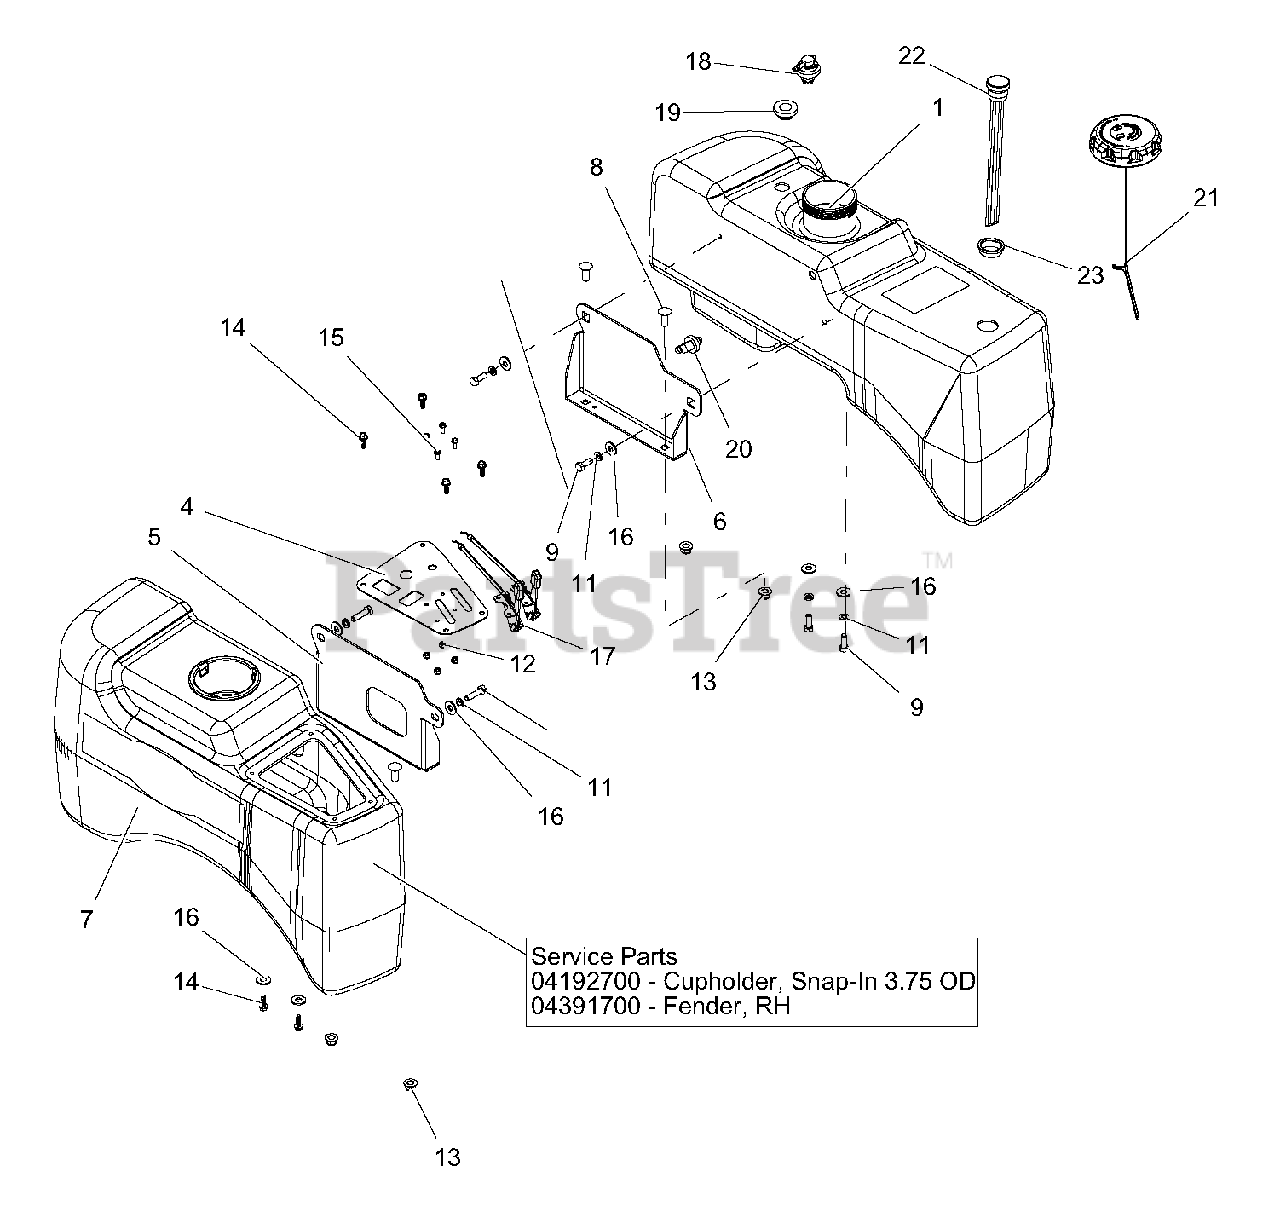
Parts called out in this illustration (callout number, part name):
1	HD, FUEL TANK ASSEMBLY
4	PANEL, INSTRUMENT-BLACK
5	BRKT, RH HD FUEL TANK MTG-RED
6	BRKT, LH HD FUEL TANK MTG-RED
7	ASM, FENDER W/CUPHOLDER
8	BLT-RDHDSQNK .38-16X1.00 G5 YWZC
9	BLT-HEX .31-18X.875 GR5 YWZC
10	BLT-HEX .31-18X1.25 GR5 YWZC
11	WSHR-LK .31X.078 REG YWZC
12	NUT-LK-NYL #10-24 YWZC
13	NUT-LK-NYL-FLG .38-16 YWZC
14	SCR-PLASTITE .25-10X.75 YWZC
15	SCR-MCH 10-24X.50 HWH YWZC
16	WSHR-FL-STL.38X.875X.083 YWZC
17	CABLE, CONTROL
18	VALVE, COMBINATION
19	GROMMET, REMOTE VENT NITRILE
20	ASS’Y, SMALL/ MED TANK FUEL PICK-UP
21	CAP, FUEL VENT-IN AUTOLOCK
22	FUEL GAGE
23	GROMMET, FUEL GAGE
